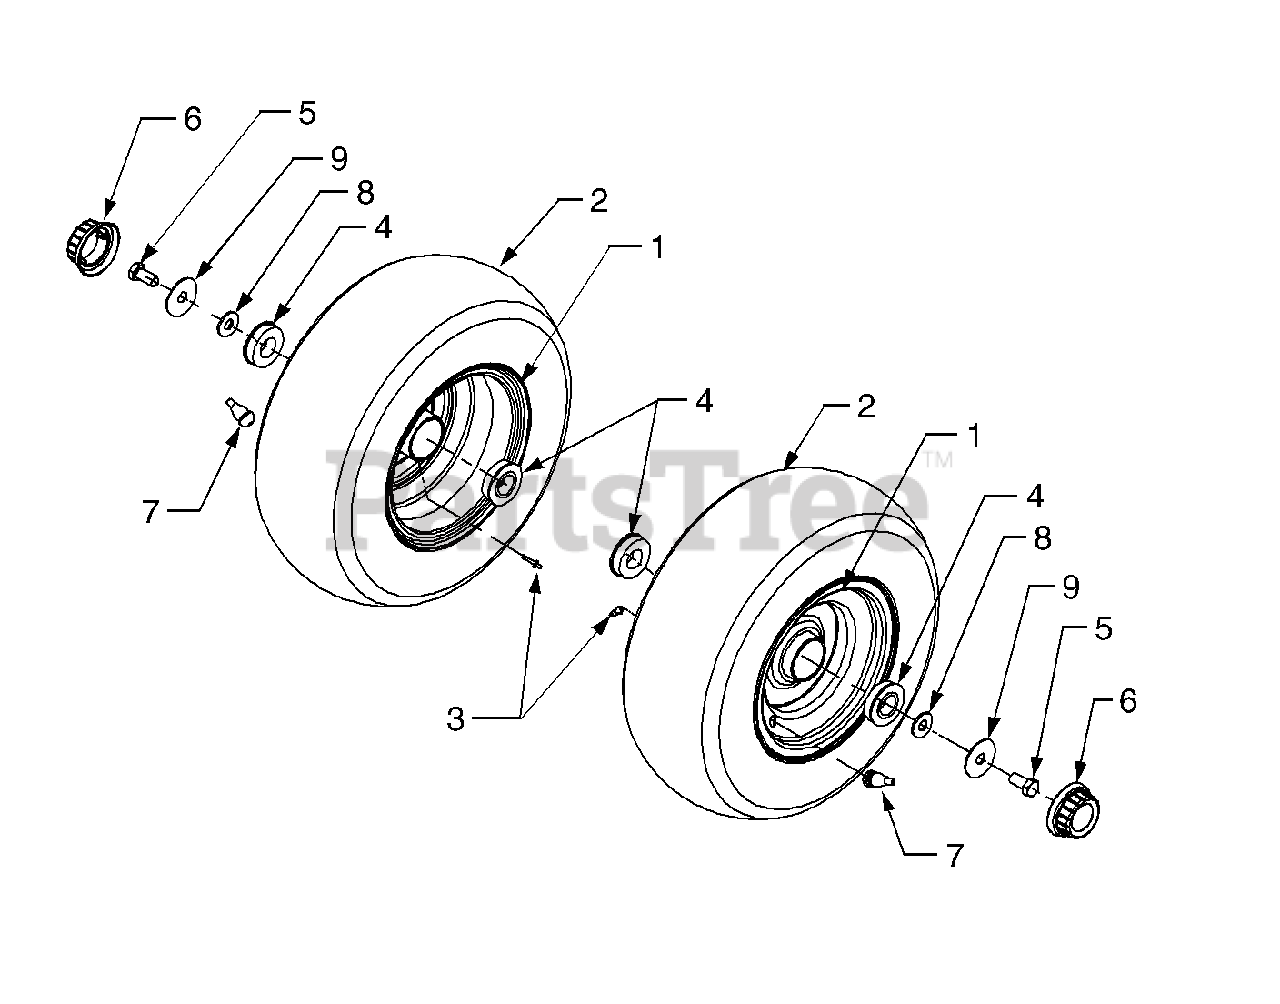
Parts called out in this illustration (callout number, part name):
1	Rim Assembly, Wheel
2	Tire, Turf, 16 x 7.5 x 8.0
3	Lube Fitting
4	Bearing, Ball
5	Screw, Hex Cap, 1/2-13 x 1.0 GR5
6	Hubcap
7	Valve, Tubeless Air
8	Washer, Flat, .531 x 1.25 x .1
9	Washer, Flat, .535 x 1.92 x .060
